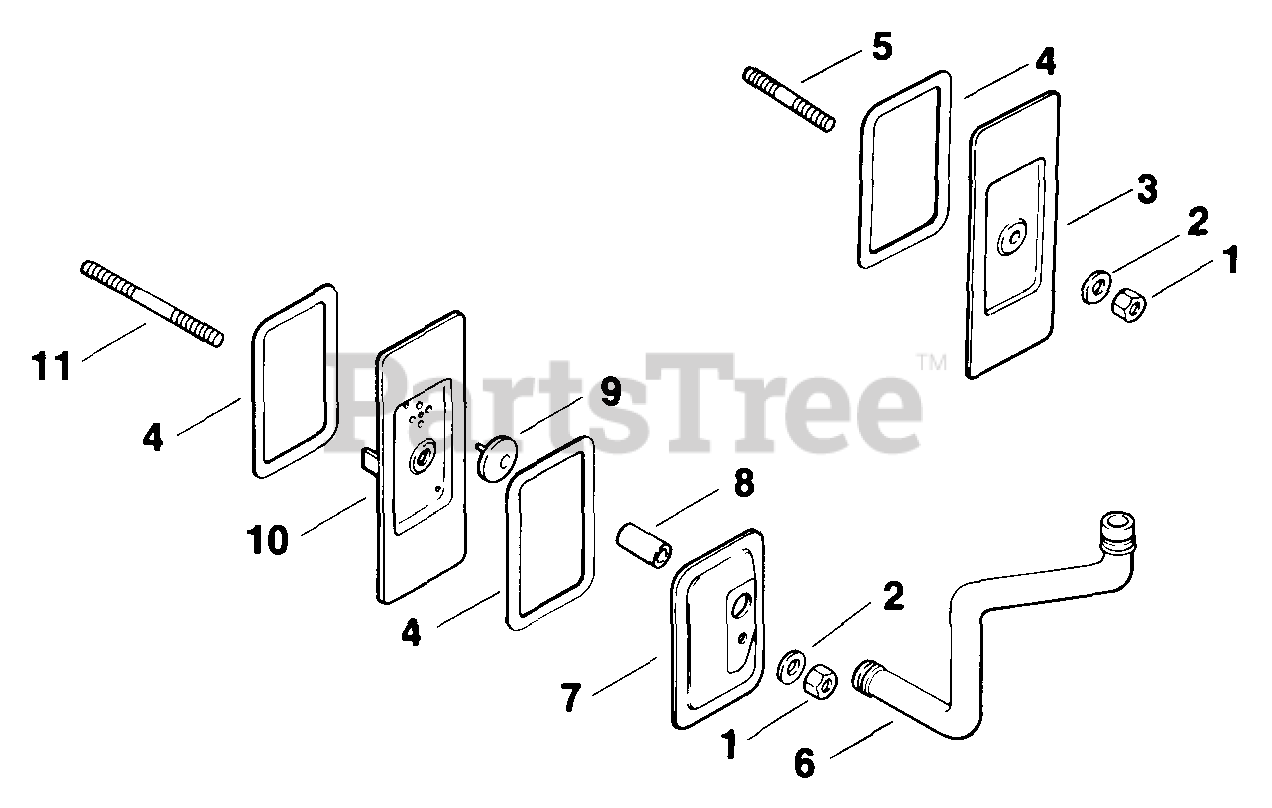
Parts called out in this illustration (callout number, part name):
1	NUT, 1/4-20 GRADE 2 USE 25 100 20-S
3	COVER - USE 52 096 55
5	STUD, 1/4-20x2-1/4" USE 25 072 11-S
6	HOSE - DISCONTINUED
9	VALVE, UMBRELLA - DISCONTINUED
10	BREATHER - USE 52 035 02
11	STUD, 1/4-20x3-1/4" - DISCONTINUED
